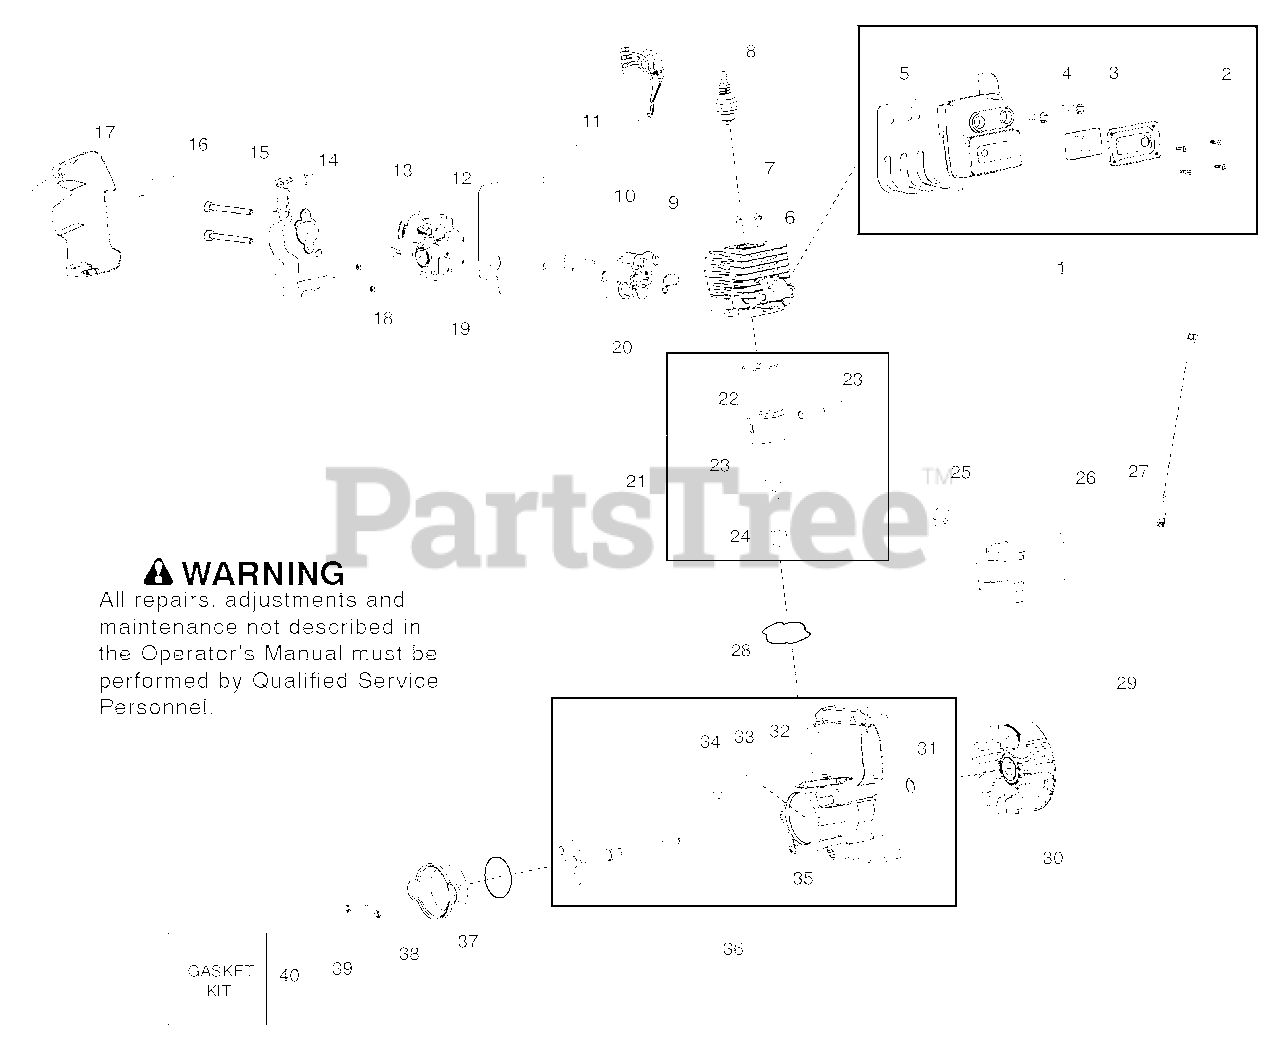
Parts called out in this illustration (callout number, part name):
1	Assy - Muffler
2	Screw
3	Kit - Spark Screen
5	Gasket-Muffler (gasket kit)
8	Spark Plug (RCJ-6Y)
9	Adapter - Carb.
11	Linkage - Throttle
12	Kit - Carb. Assy (WT847)
13	Lever- Choke (Gold)
14	Base - Airbox
17	Cover - Air Box Filter
18	Bulb - Purge (walbro 188-16)
19	Gasket (Carb / Adapter) (gasket kit)
20	O-Ring (Adapter / Cylinder) (gasket kit)
21	Kit - Piston / Connecting Rod
22	Ring - Piston
23	Retainer - Wrist Pin
24	Kit - Assy. Connecting Rod
25	Module - Ignition
27	Assy - Wire Harness
28	O-Ring (Cyl/Crankcase) (gasket kit)
30	Assy - Flywheel
31	Retainer - Crankshaft
32	Bearing - Outer
34	Bearing - Inner
35	Assy - Crankcase
36	Assy - Crankcase & Crankshaft
37	O-Ring (Rear Plug) (gasket kit)
38	Assy - Rear Plug
40	Kit - Gasket
